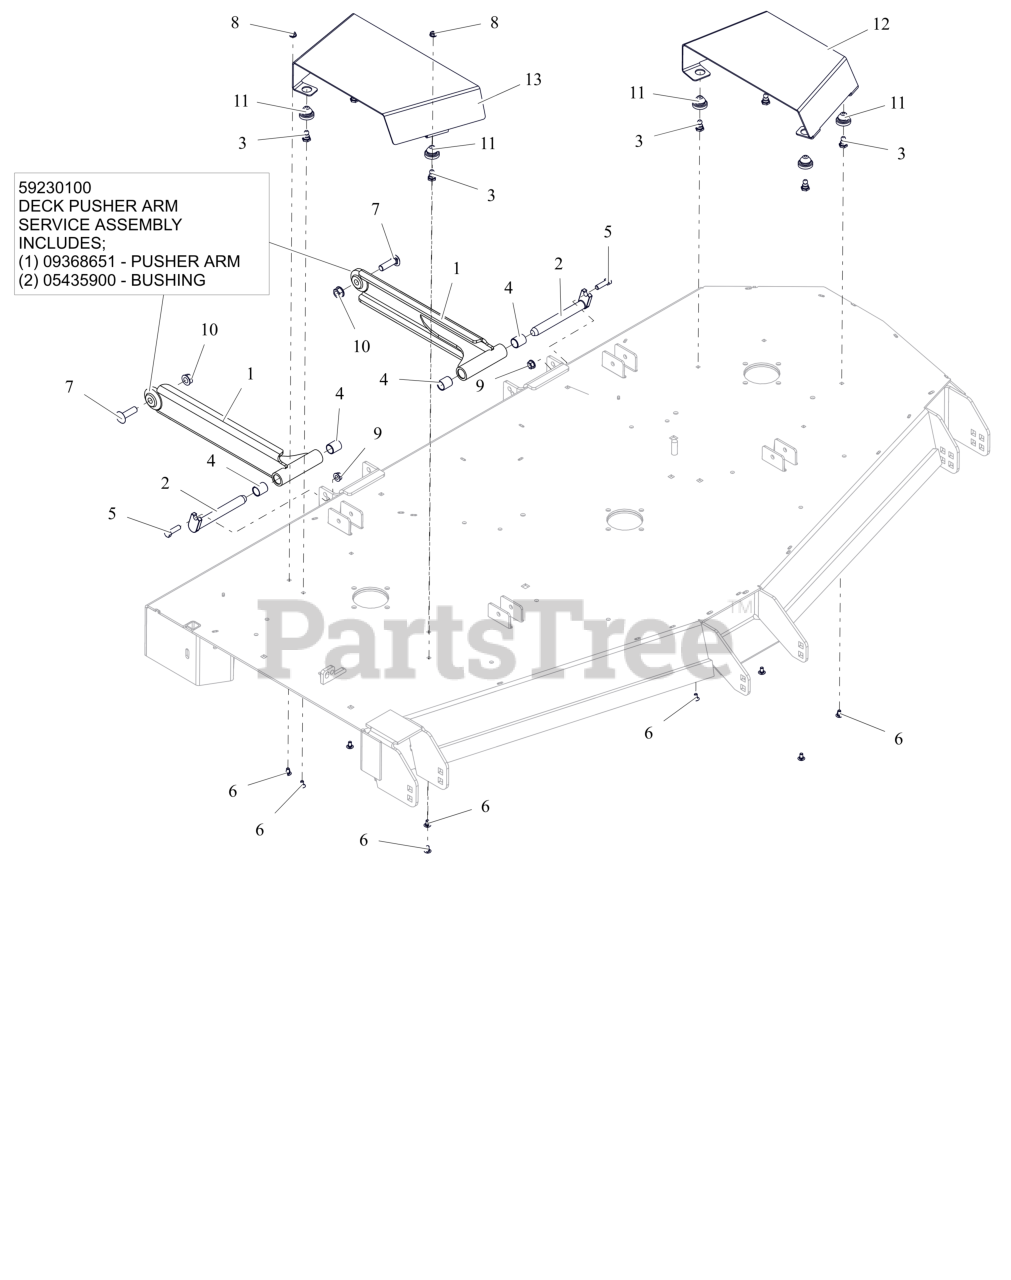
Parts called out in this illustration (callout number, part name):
1	WLDMT, DECK STABILIZER ARM (BLACK)
1	DECK PUSHER ARM SERVICE ASSEMBLY
1	BRG, .750 X .875 X 1.000
2	PIN, MOWER MTG
3	STUD, BALL FEMALE .250-20 THREAD
4	BRG, .750 X .875 X 1.000
5	BLT, HEX .38-16X1.25 G5 ZCC
6	BLT, RHSSN.25-20X.500 G5 ZCC
7	BTL,RHSSN .500-13 X 1.75 G5 ZCC
8	NUT-LK-CTR-FLG .25-20 ZC120
9	NUT-LK-CTR-FLG .375-16 GF ZCC
10	NUT-LK-CTR-FLG .500-13 GG ZCC
11	COUPLING, RUBBER PUSH-IN
12	GUARD, LH DECK BELT 72" (RED)
13	GUARD, RH DECK BELT 72" (RED)
